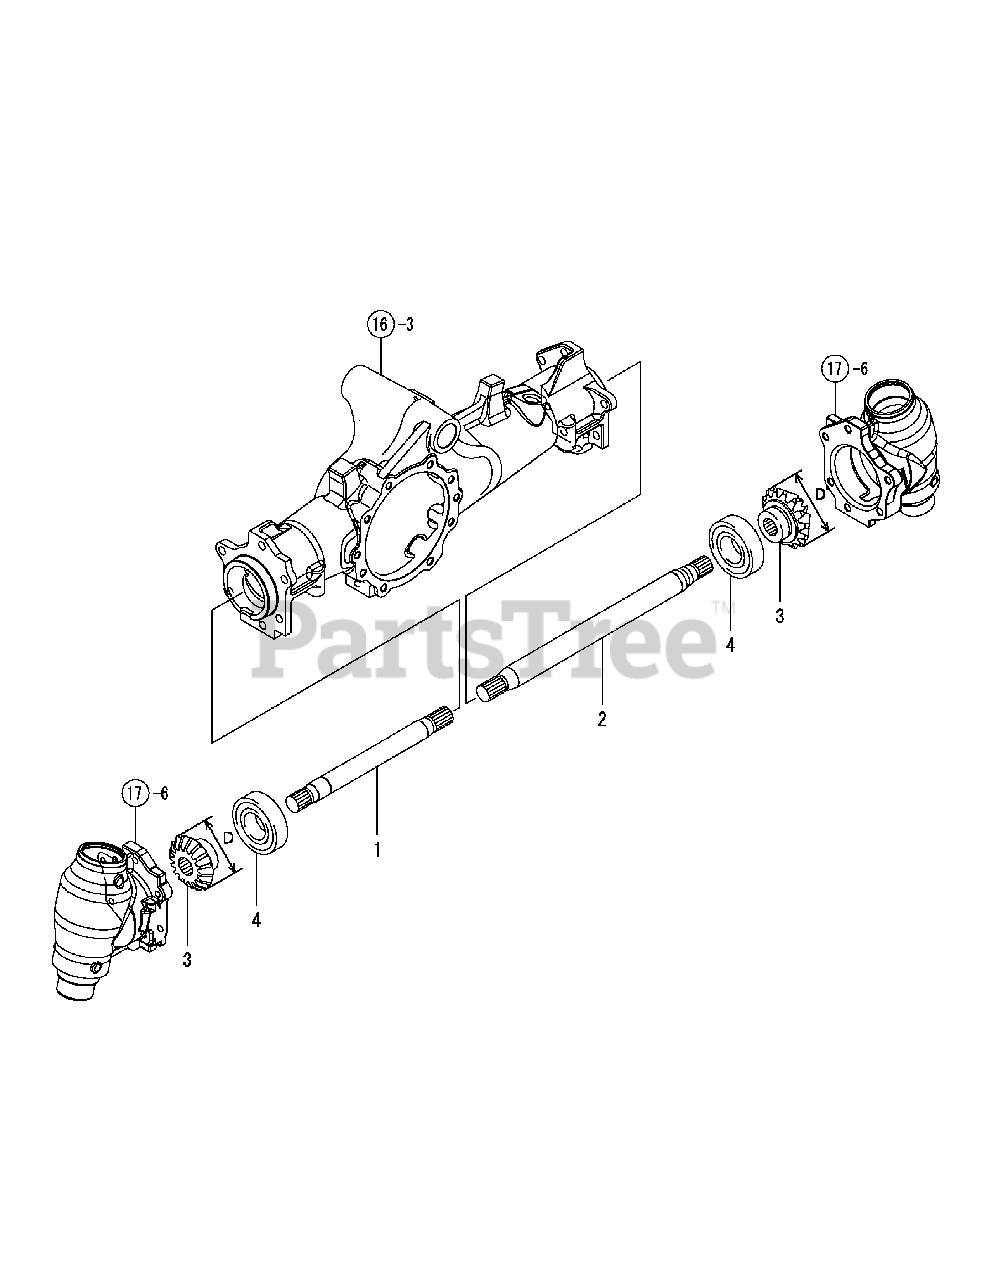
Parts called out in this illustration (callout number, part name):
1	SHAFT, DRIVE L.H.
2	SHAFT, DRIVE R.H.
3	PINION, FRONT 1ST D=72MM
3-1	PINION, FRONT 1ST D=70MM
